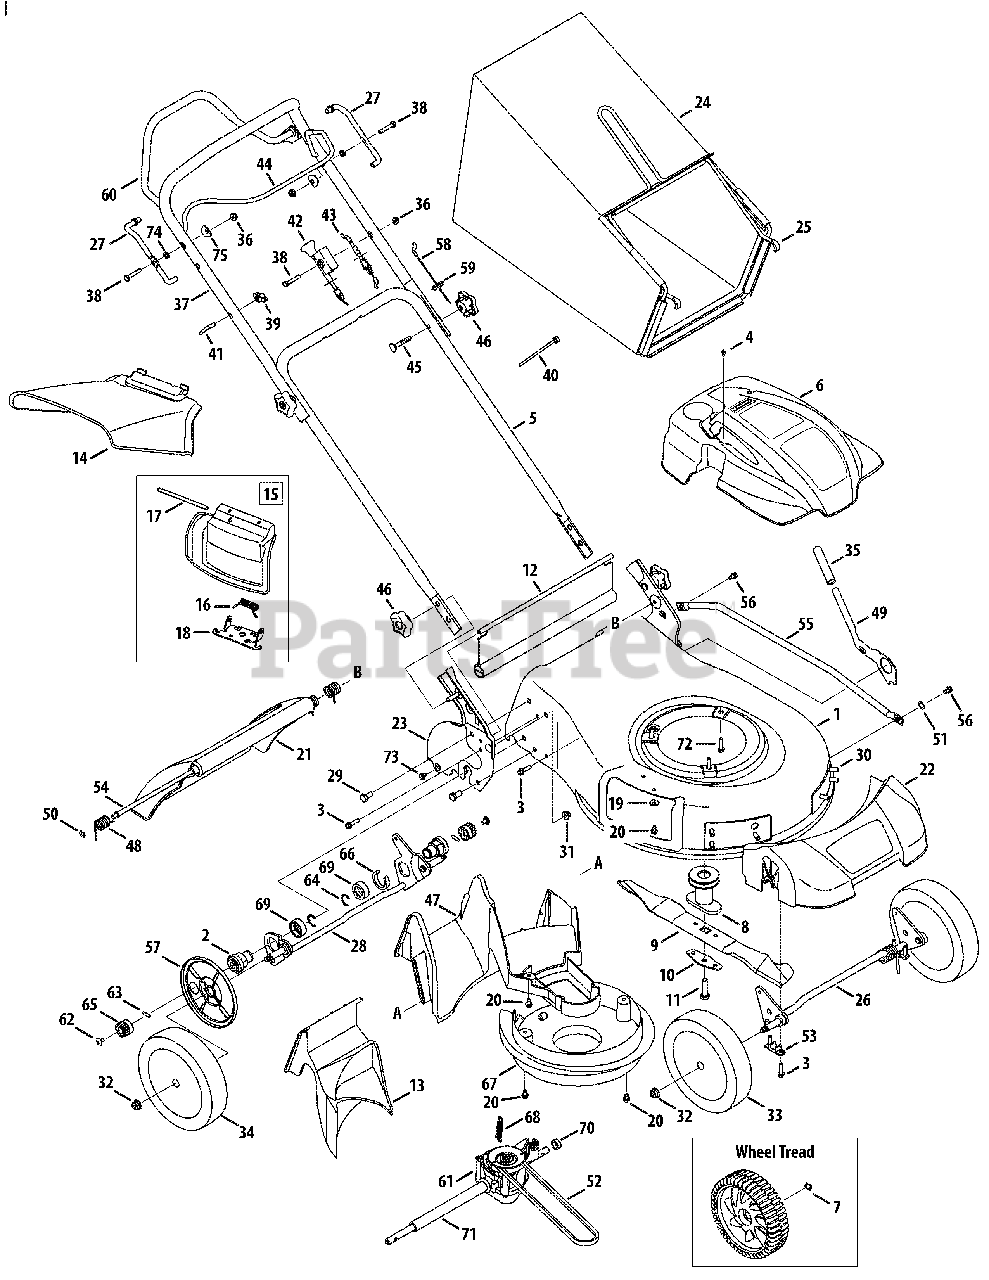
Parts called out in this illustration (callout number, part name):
3	Screw, 1/4-15 x 1.000
4	Screw, Machine, M4-.7 x 10.00
6	Engine Shroud
7	Washer, Wave, .510 x .750 x .017
8	Blade Adapter
9	Mulching Blade
10	Blade Bell Support
11	Screw, 3/8-24 x 1.50
12	Trailing Shield
13	Rear Mulch Plug
14	Side Discharge Chute
15	Mulch Plug (Incl. 16-18)
16	Torsion Spring
17	Hinge Pin
18	Chute Deflector Adapter
19	Beleville Washer
21	Rear Door
22	Front Cover
27	Drive Control Pivot Rod - LH
27	Drive Control Pivot Rod - RH
29	Hhcs, 5/16-18 x .625
30	Screw, 5/16-14 x .750
31	Nut, Flange Lock, 5/16-18
32	Nut, Flange Lock, 3/8-16
33	Front Wheel
34	Rear Wheel
35	Foam Grip
36	Nut, Flange Lock, 1/4-20
40	Cable Tie
41	Rope Guide
42	Choke Cable
43	Control Cable
45	Bolt Carriage, 5/16-18 x 2.0
46	Star Knob
47	Rear Baffle
48	Door Torsion Spring - RH
48	Door Torsion Spring - LH
49	Spring Lever
51	Washer, Wave, .390 x .825 x .016
52	V-Belt
53	Bushing, Lock, .505 Dia. X .62
54	Rear Door Pivot Rod
56	Scr., Shldr., 1/4-20 x .50
57	Wheel Dust Cover
58	Drive Cable
62	Screw, 1/4-20 x .390
63	Dowel Pin
64	Retainer Ring
65	Spur Gear - RH
65	Spur Gear - LH
66	Spacer, Clip
67	Engine Baffle
68	Extension Spring, .429OD x 2.515
69	Bearing Support Spacer
70	Sleeve Spacer, .550ID x .340 Lg.
71	Sleeve Spacer, .550ID x 7.97 Lg.
72	Screw, 3/8-16 x 1.00
73	Screw, #10-16 x .375
74	Washer, Lock, 1/4
75	Washer, Saddle
